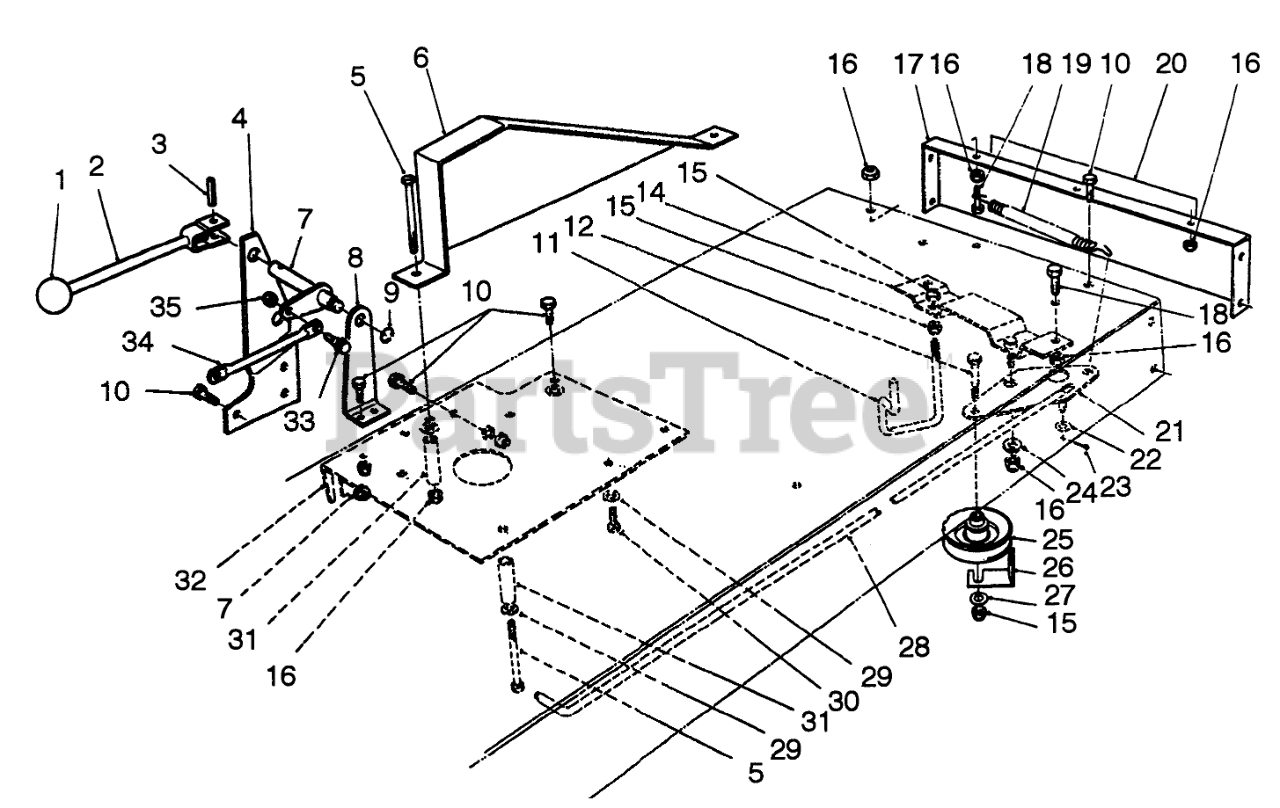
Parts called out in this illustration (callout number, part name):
2	Lever W.A.-Engage
3	PIN-ROLL
4	Pivot-Outer
5	SCREW-HH
6	CHAIN GUARD R
7	PIVOT SHAFT WA
8	Bracket-Pivot, Inner
9	RING-RETAINING, EXTERNAL
10	SCREW-HH
11	BELT GUIDE
12	SCREW-HH
14	TRACT SUPT BRKT WA B
15	NUT-LOCK, NI
16	NUT-LOCK, NI
17	REAR FRAME R
18	SCREW-HH
19	TRACTION SPRING
20	DECAL - REAR FRAME
21	TRACT PIVOT BRKT B
22	WASHER-FLAT
23	PIN-COTTER
24	WASHER-FLAT
25	PULLEY-IDLER
26	RETAINER-BELT
27	WASHER-FLAT
28	TRACTION ROD
29	WASHER-PLAIN
30	SCREW-HH
31	OUTER TUBE SPACER
32	REINF PLATE R
33	SCREW-SHOULDER
34	LINK-BELLCRANK
35	NUT-HEX
